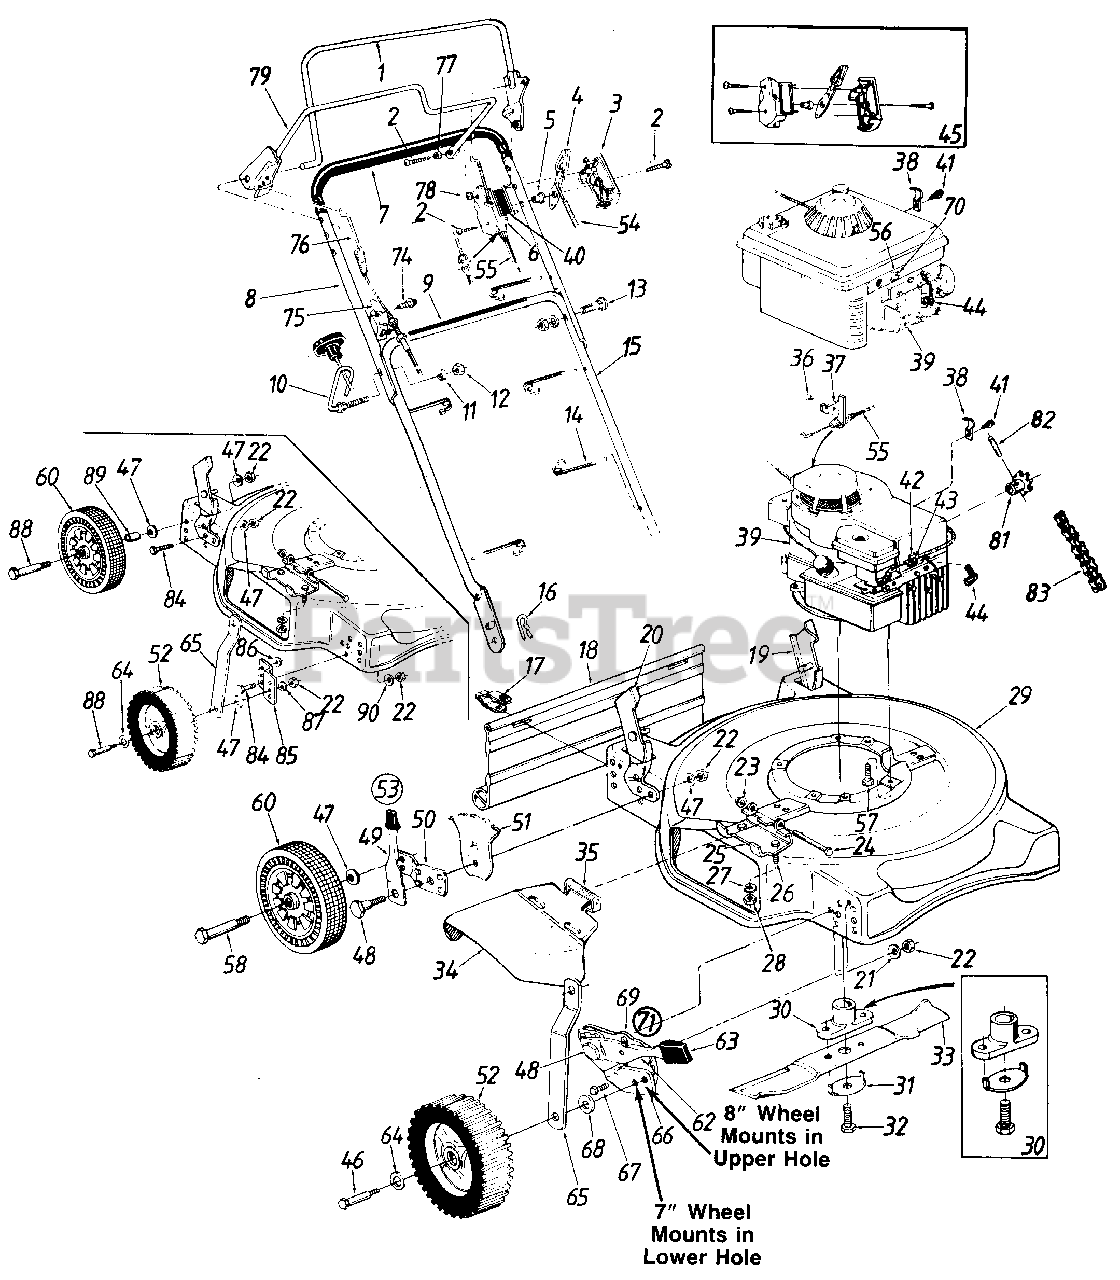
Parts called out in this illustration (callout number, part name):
1	Control Handle Ass'y.
2	Truss Mach. Scr. #12 x 1.5
3	Control Panel Half
4	Throttle Control Lever
5	Control Disc Pin
6	Clutch Panel Half
8	Upper Handle
9	Instruction Label-Handle
10	Rope Guide Bolt
11	L-Wash. 5/16" I.D.
12	Hex Nut 5/16-18 Thd.
13	Curved Carriage Bolt 5/16-18 x 1.38" Lg.
14	Cable Tie
15	Lower Handle
16	Hairpin Cotter
17	Hinge Clip
18	Rear Flap
19	Handle Bracket Ass'y.-L.H.
20	Handle Bracket Ass'y.-R.H.
21	Bell-Wash. .39" I.D. x 1.38"
22	Hex Nut 3/8-16 Thd.
23	Push Cap 1/4" Rod
24	Pivot Pin
25	Adapter Plate
26	Hex Bolt 1/4-20 x .50" Lg.
27	L-Wash. 1/4" I.D.
28	Hex Nut 1/4-20 Thd.
29	22" Deck Ass'y.
30	Blade Adapter Kit
31	Blade Bell-Wash. .45" I.D.
32	Hex Bolt 3/8-24 x 1.5" Lg.
33	22" Blade
34	Chute Deflector Ass'y.
35	Torsion Spring
36	Pop Rivet
37	Cable Bracket
38	Cable Clamp
39	Engine
40	Throttle Label
41	Hex B-Tap Scr. #10 x .38"
42	Cable Clamp
43	Hex AB-Tap Scr. #8 x 38" Lg.
44	Spark Plug Boot
45	Kit-Control Housing Comp.
46	Front Axle Bolt
47	Bell-Wash. .400" I.D. x .88"
48	Shld. Bolt .50" Dia. x .357"
49	Spring Lever Ass'y. w/Knob
50	Pivot Bar
51	Height Adj. Plate
52	Front Wheel Ass'y. Comp. (Plastic)
53	Height Adj. Ass'y. Comp.-R.H .
54	Throttle Wire-53"
55	Control Cable-39"
56	Cable Clamp
57	Hex L-Wash. HD. Scr. 3/8-16 x 1.0" Lg.
58	Rear Axle Bolt
60	Rear Wheel Ass'y. Comp.
62	Spring Lever
63	Spring Lever Knob
64	Fl-Wash. .531" I.D. x .93"
65	Link 4.58" Lg.
66	Pivot Bar R.H.
67	Hex AB-Tap 1/4-.62" Lg.
68	Bell-Wash. .380" I.D. x .88"
69	Index Plate
70	Hex B-Tap Scr. #10 x .62"
71	Front Height Adj. Ass'y.-R.H.
74	Hex Wash. AB-Tap Scr. 5/16 x.75" Lg.
75	Cable Brkt.
76	Clutch Cable w/Spring-49"
77	Spacer .23" I.D. x .30" O.D.
78	Spr.-Wash. .206" I.D. x .448
79	S.P. Bail Ass'y.
81	10 Tooth Sprocket Ass'y.
82	Spring Pin Spir. 3/16" Dia. x 1 " Lg.
83	#48 Chain 1/2" Pitch 50 Links (Endless)
84	Hex Bolt 3/8-16 x .75" Lg.
85	Wheel Bracket
86	Fl-Wash. .385" I.D.
87	L-Wash. 3/8" I.D.
88	Axle Bolt
89	Spacer .511" I.D.
90	Bell-Wash. .39" I.D.
